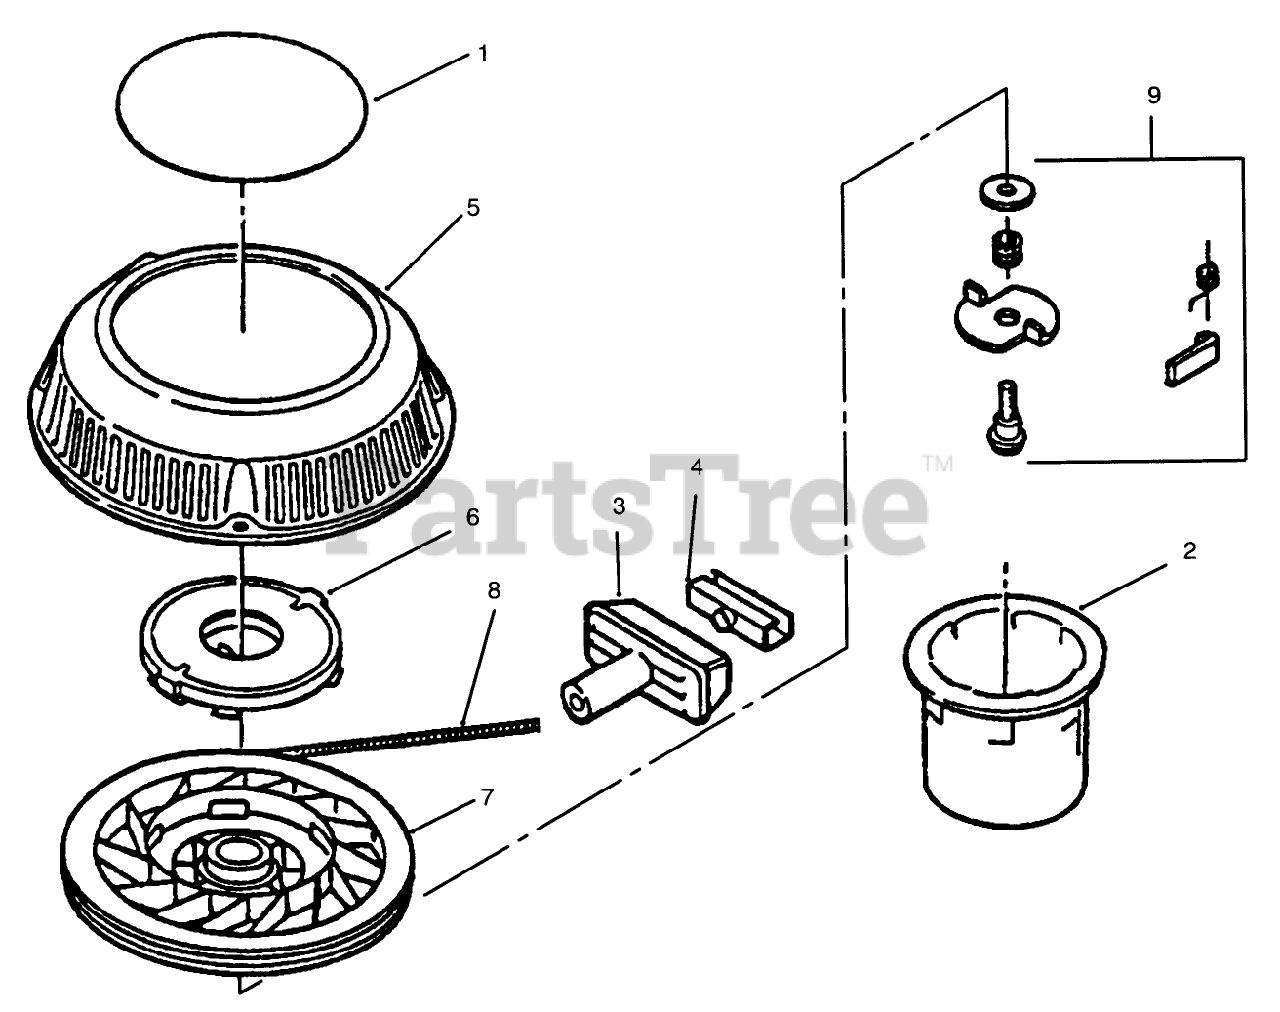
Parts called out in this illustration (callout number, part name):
2	HUB-STARTER E COMM.
4	CLIP-STARTER
5	STARTER HOUSING & SHAFT
6	SPRING KEEPER ASM
9	DOG KIT
